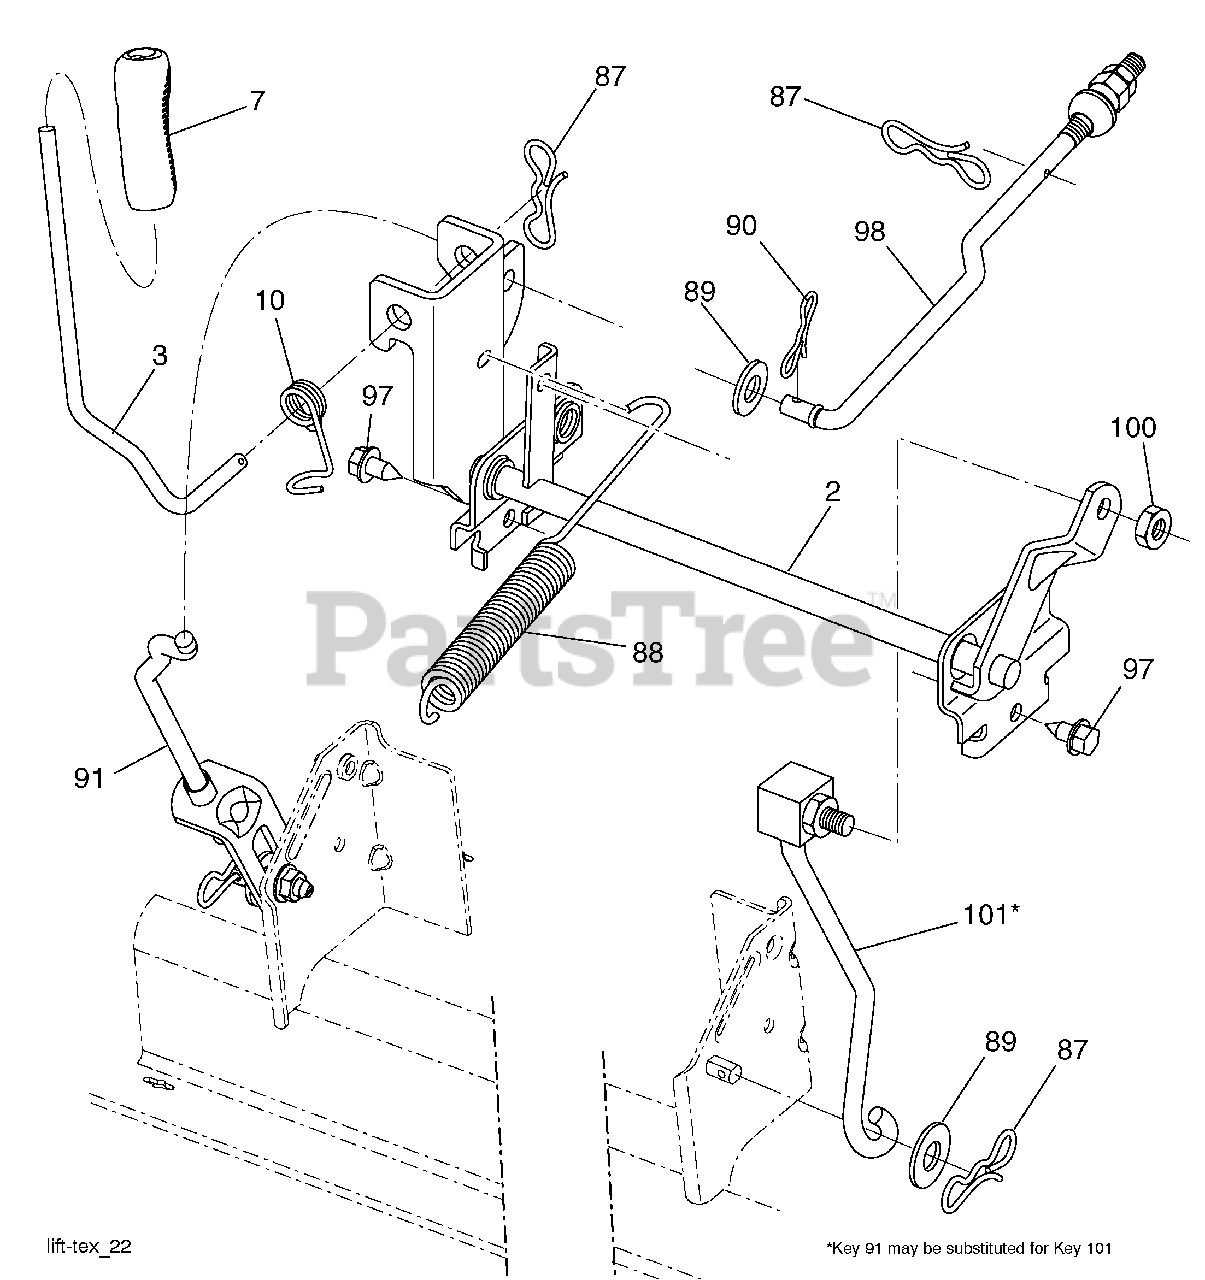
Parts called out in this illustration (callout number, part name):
2	Shaft Asm., Lift
3	Lever Asm., Lift RH
7	Grip, Lever
10	Spring Torsion
87	Pin Cotter 7/16 Bow Tie Lock
88	Spring Lift Assist
89	Washer Clear Zinc
90	Pin Cotter 5/16 Bow Tie Lock
91	Link Asm Lift LH Rear
97	Screw Hex Wsh. THDR 3/8-16 x 3/4
98	Link Lift Susp. Front Mower
100	Nut Centerlock 3/8-16 unc
101	Link Asm. Lift FXD
